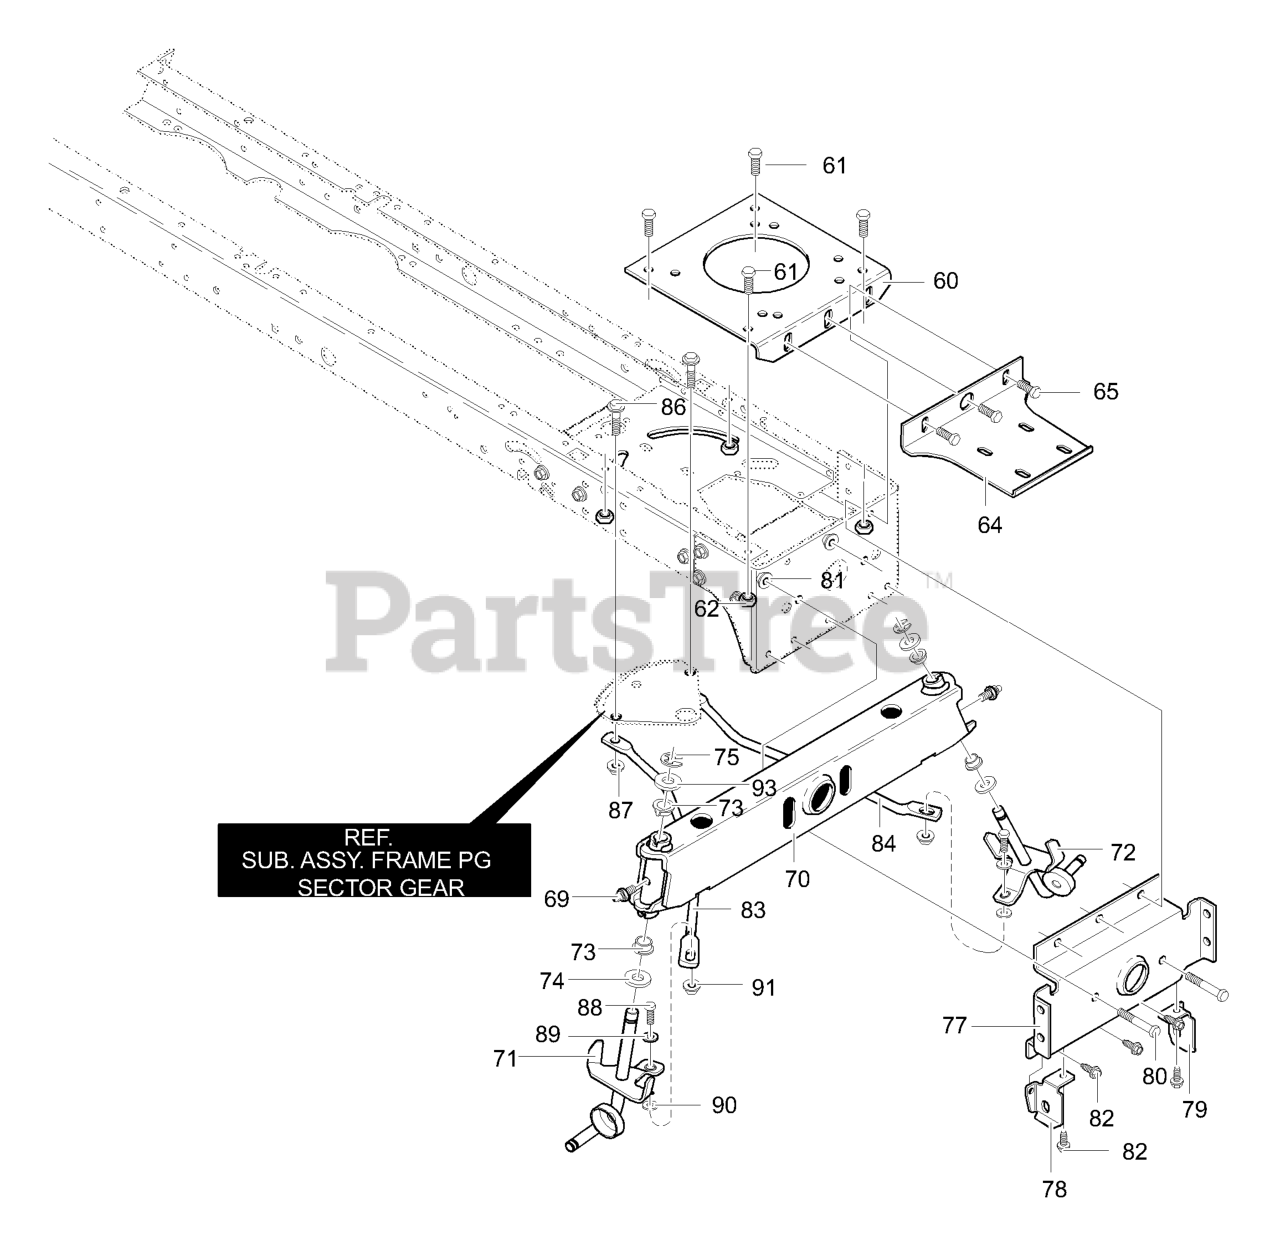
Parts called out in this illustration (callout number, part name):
60	Engine Plate
61	Screw, .312-18x.75
62	Nut, 5/16-18
64	Bracket, Muffler Mount
65	Screw, .312-18x.75
69	Zerk, Grease Fitting
70	Axle, Cast Machined
71	Spindle, RH
72	Spindle, LH
73	Bearing, Spindle
74	Washer, .766IDx1.62ID
77	Hanger, Axle
78	Hanger, Deck RH
79	Hanger, Deck LH
80	Screw, 5/16-24 x 2.75
81	Nut, .32-24 Flangelock
82	Screw, .5/16-24X2.75
83	Drag Link, RH
84	Drag Link, LH
86	Shoulder Bolt
87	Nut, 3/8-16
88	Screw, 3/8-16 x 1.50
89	Flatwasher
90	Flatwasher
91	Nut, 3/8-16
93	Flat washer
